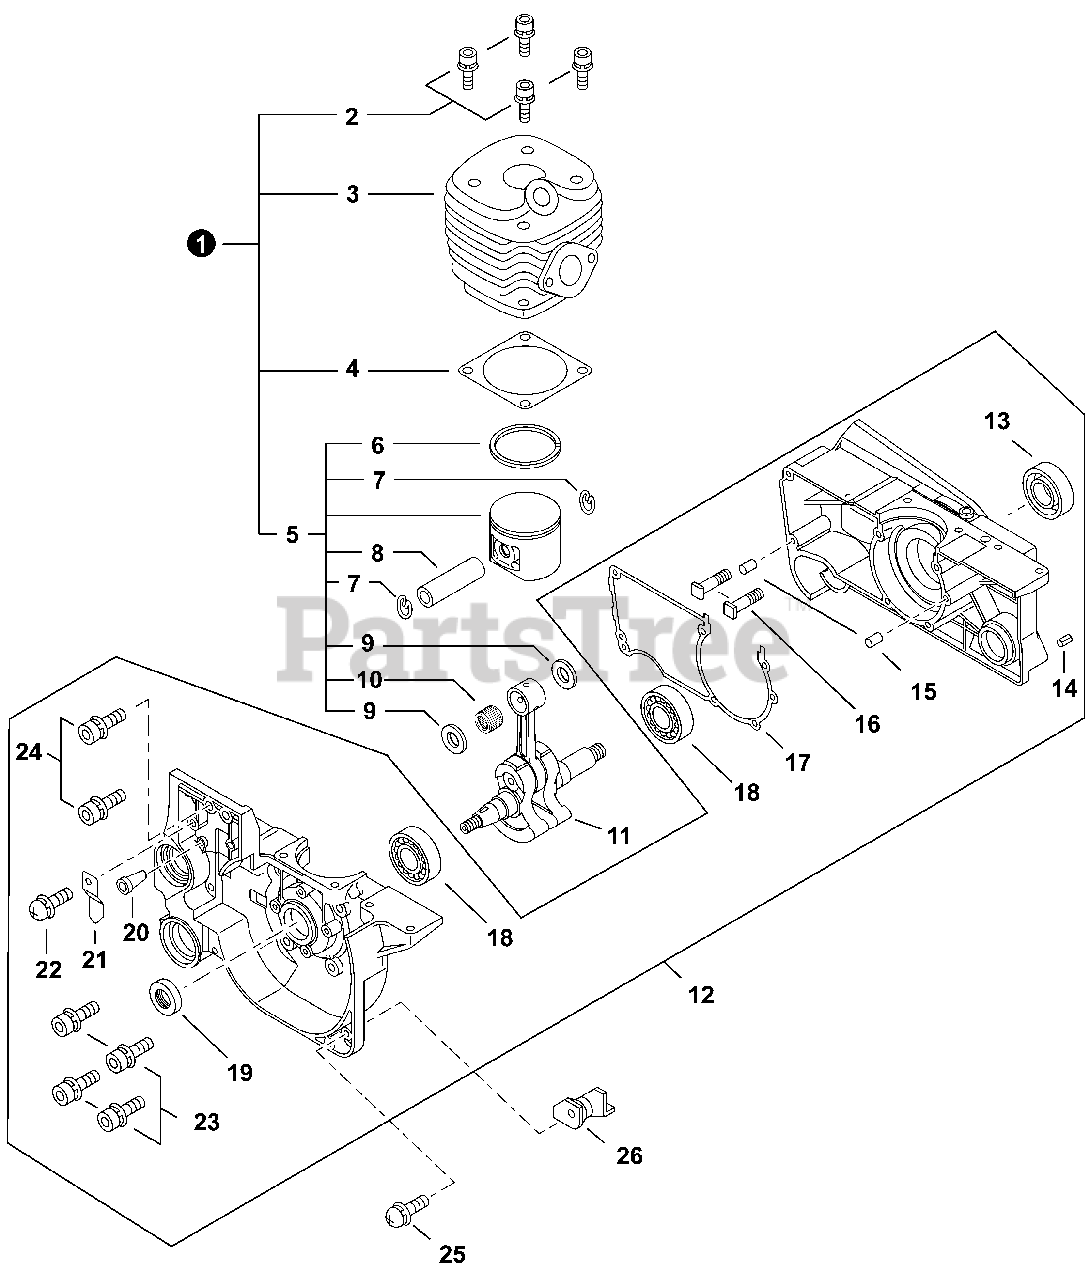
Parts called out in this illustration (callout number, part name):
1	REPAIR KIT, ENGINE
2	BOLT 5×25
3	CYLINDER
4	GASKET, CYLINDER
5	PISTON KIT
6	RING, PISTON
7	RING, SNAP
8	PIN, PISTON 12
9	WASHER, THRUST
10	BEARING, NEEDLE
11	CRANKSHAFT ASSY
12	CRANKCASE KIT
13	SEAL, OIL
14	PIN, SPRING Ø5×25 MM
15	PIN, LOCATING 5×10
16	STUD, GUIDE BAR 8
17	GASKET, CRANKCASE
18	BEARING, BALL 6202
19	SEAL, OIL
20	VENT ASSY
21	PLATE, EYE
22	SCREW 4×8
23	BOLT M5×35
24	BOLT 5×20
25	SCREW 5×14
26	CUSHION 5
